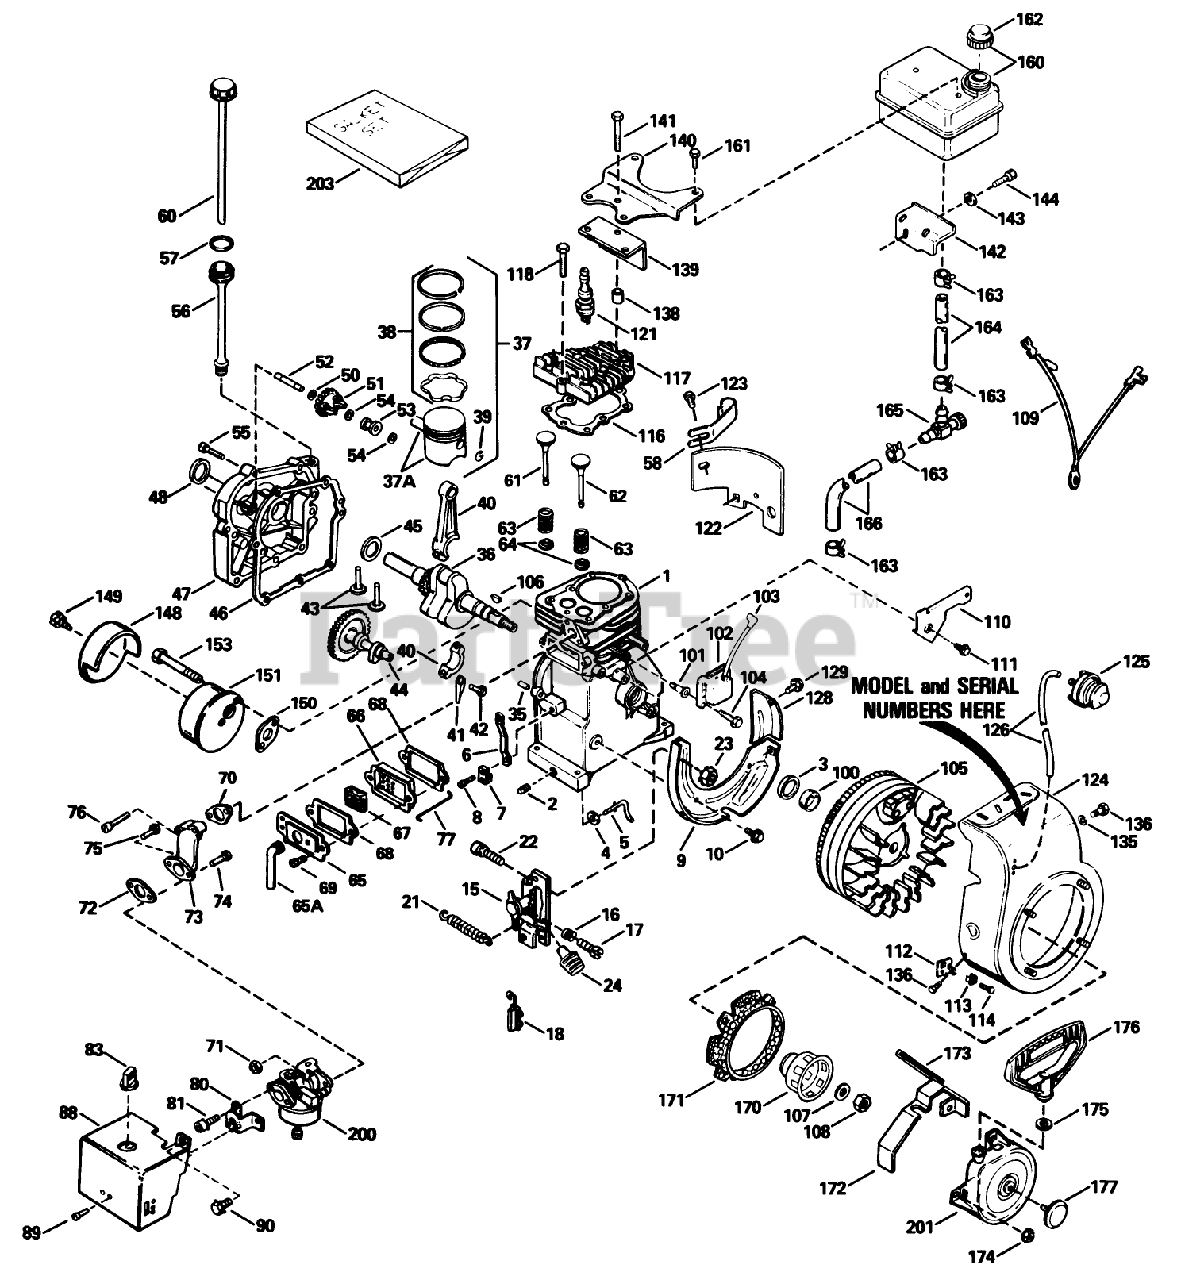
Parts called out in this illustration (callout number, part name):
1	Cylinder Assembly (Incl. Ref. #2, 3 35)
2	Plug-Drain, Oil (SQH 1/4-18)
3	Seal-Oil
4	Washer-Flat
5	Rod-Governor
6	Lever-Governor
7	Clamp-Lever, Governor
8	Screw
9	Baffle-Blower Housing
10	Screw (1/4-20x19/32)
15	Control Assembly, Speed (Incl. Ref. #155 thru 158 160)
16	Spring-Compression
17	Screw
18	Terminal
21	Spring-Extension
22	Screw
23	Nut-Lock
24	Knob-Control
35	Pin-Dowel
36	Crankshaft
37	Piston-Pin Ring Assy. (Std.)(Incl. Ref. #14A, 15 16)
37	Piston-Pin Ring Assy. (.010 oversize)(Incl. Ref. #14A, 15 16)
37	Piston-Pin Ring Assy. (.020 oversize)(Incl. Ref. #14A, 15 16)
37A	Piston Pin Assy. (Std)(Incl. Ref. #16)
37A	Piston Pin Assy. (.010 oversize) (Incl. Ref. #16)
37A	Piston Pin Assy. (.020 oversize) (Incl. Ref. #16)
38	Piston Ring Set Std.
38	Piston Ring Set .010 O.S.
38	Piston Ring Set .020 O.S.
39	Ring-Retaining, Piston Pin
40	Rod Assembly, Connecting (Incl. Nos. 17 18)
41	Dipper-Oil
42	Bolt-Rod, Connecting
43	Lifter-Valve
44	Camshaft (Compression Release)
45	Washer-Thrust
46	Gasket-Cylinder Cover
47	Cover-Cylinder (Incl. Ref. #59 72)
48	Seal-Oil
50	Washer-Flat
51	Governor Gear ASM
52	Shaft-Governor
53	Spool-Governor
54	Ring-Retaining
55	Screw (1/4-20 x 1-1/4)
56	Tube-Fill, Oil
57	O-Ring
58	Clip-Tube, Fill
60	Dipstick
61	Valve, Exhaust (Std.)(Incl. No. 40)
61	Valve, Intake (1/32" oversize)(Incl. No. 40)
62	Valve, Intake (Std.) (Incl. Ref. #40)
62	Valve, Intake (1/32" oversize)(Incl. No. 40)
63	Spring-Valve
64	Cap-Valve, Spring
65	Cover-Breather
65A	Tube-Breather
66	Body-Breather
67	Element-Breather
68	Gasket-Breather
69	Screw
70	Gasket-Intake
71	Nut and Lock Washer (1/4-28)
72	Gasket
73	Pipe-Intake (Incl. Ref. #47)
75	Screw-Hex Hd.
76	Screw (1/4-20 x 1-19/32)
77	Jet-Main
80	Bracket-Choke
81	Screw (10-32 x 1/2)
83	Knob-Choke
88	Cover-Carburetor
89	Screw (8-32 X 5/16)
90	Screw (10-32x1/2)
100	Spacer
102	Solid State
103	Cover-Spark Plug
104	Screw
105	CLAMP
106	Key-Flywheel
107	Washer-Belleville
108	Nut-Flywheel
109	Wire-Ground
110	Bracket-Hold Down
111	Screw (10-24 x 9/16)
112	Bracket
113	Grommet
114	Screw (8-32 x 3/8)
116	Gasket-Cylinder Head
117	CYLINDER HEAD
118	Screw (5/16-18x1-1/2)
121	Spark Plug-Resistor (R J19 L M)
122	Extension-Blower
123	Screw
124	Housing-Blower
125	Primer-Asm
126	Line-Primer
128	Baffle-Extension
129	Screw-Hex Washer Hd.
135	Washer
136	Screw
138	pacer
139	Baffle-Heat
140	Plate-Fuel Tank
141	Screw (5/16-18 X 2)
142	Bracket-Fuel Tank
143	Washer
144	Screw Assembly
148	Cover-Muffler
149	Screw (1/4-15x7/8)
150	Gasket Exhaust
151	Muffler
153	Screw
160	481-1261 SENATOR TI
161	Screw (1/4-15x7/8)
162	Cap, Fuel
163	Clamp-Line, Fuel
164	Line-Fuel (8.62)
165	Valve-Shut Off
166	Line-Fuel
170	Cup-Starter
171	Screen-Starter
172	Guard-Starter
173	Seal, Snowguard
174	Nut and Lock Washer (1/4-28)
175	Washer
176	Handle-Starter, Mitten Grip
177	Plug-Starter
200	Carburetor (Incl. Ref. #87)
201	Starter-Rewind
203	Gasket Set (Incl. items marked*
